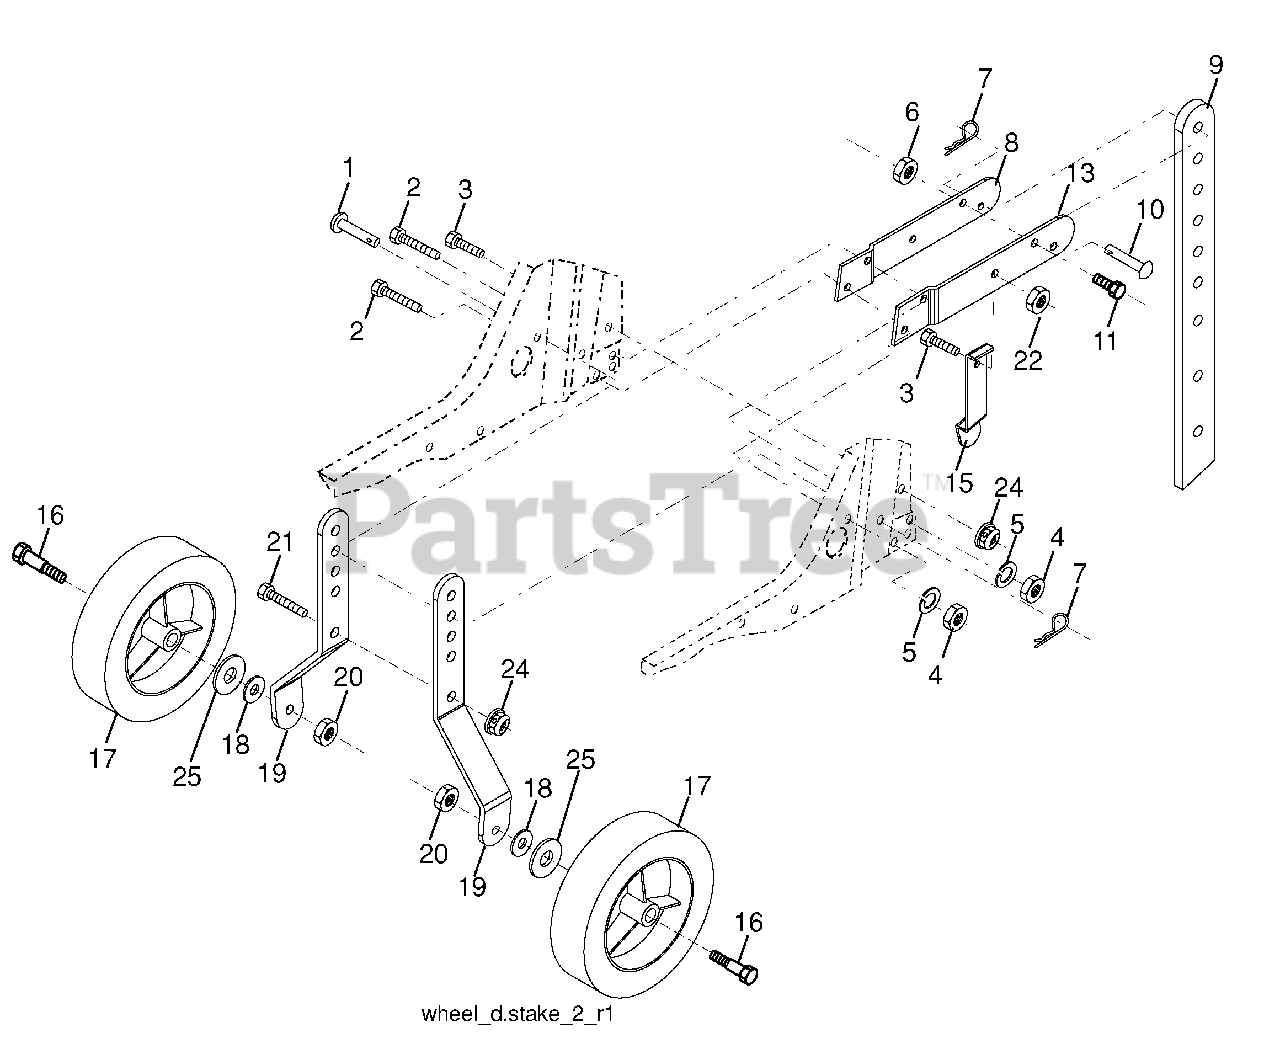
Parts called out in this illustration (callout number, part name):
1	Pin, Clevis
2	Bolt, Hex Head 5/16-18 x 1-1/4
3	Bolt, Hex Head 5/16-18 x 3/4
4	Nut, Hex 5/16-18
5	Washer, Lock 5/16
6	Locknut, Washer Insert 3/8-16
7	Clip, Hairpin
8	Support, Depth Stake, R.H.
9	Stake, Depth
10	Pin, Clevis
11	Bolt, Hex Head 3/8-16 x 1-3/4
13	Support, Depth Stake, L.H.
15	Spring, Stake
16	Bolt, Shoulder
17	Wheel
18	Washer 13/32 x 13/16 x 11 Ga.
19	Bracket, Wheel
20	Nut, Hex, Crownlock 3/8-16
21	Bolt, Hex Head 5/16-18 x 1
22	Locknut, Washer Insert 5/16-18
24	Nut, Hex, Flangelock
25	Washer, 17/32 x 7/8 x 16 Ga.
